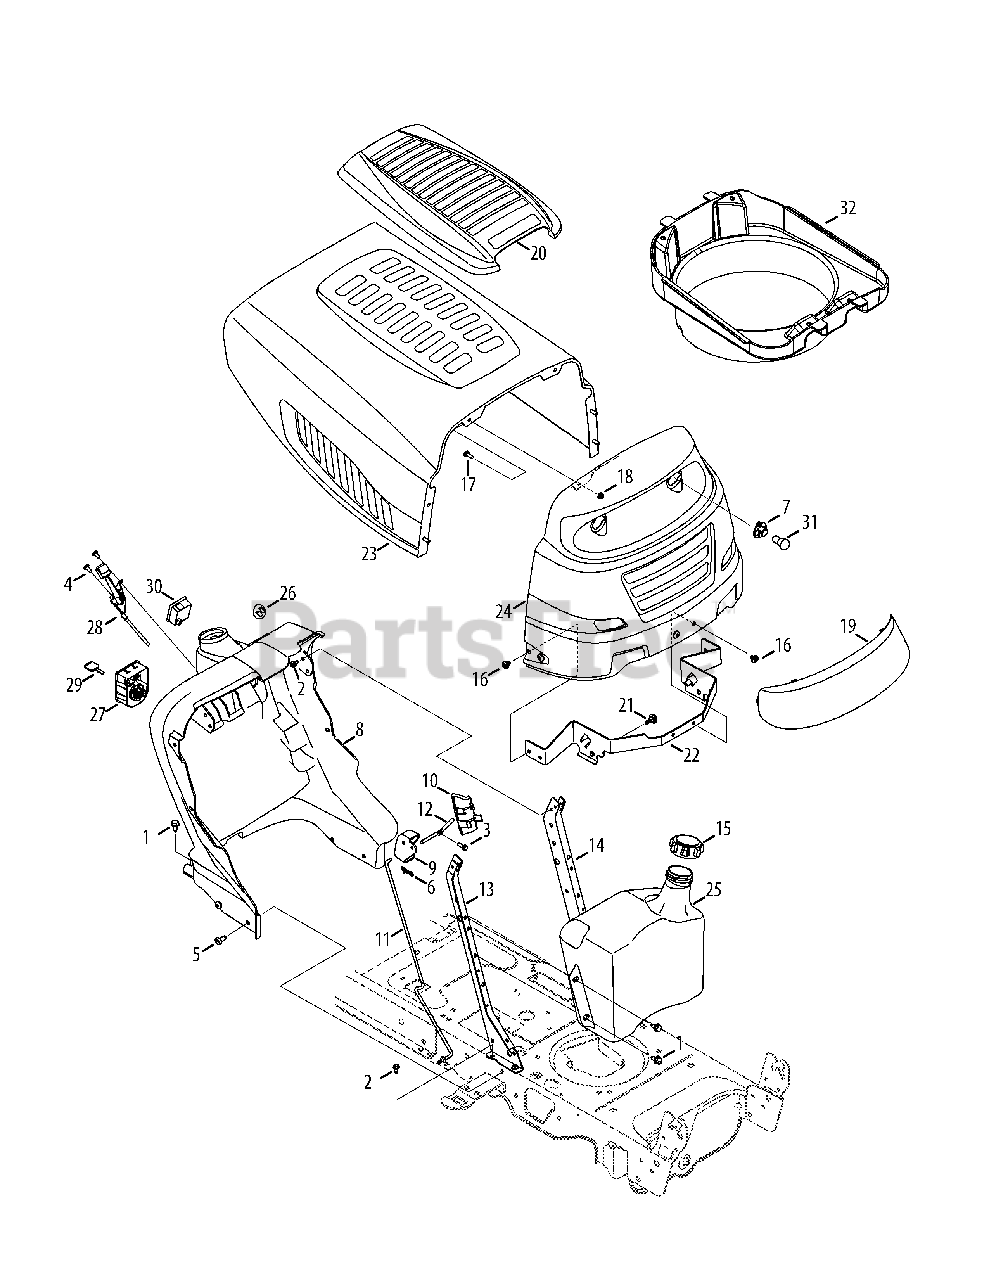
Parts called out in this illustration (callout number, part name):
1	Taptite Screw ,5/16-18x.750
2	Taptite Screw ,1/4-20x0.500
3	Hi-Lo Screw, 1/4-15x0.750
4	Screw, 1/4-14x0.625
5	Taptite Screw ,5/16-18x0.750
6	Bow Tie Cotter Pin
7	Lamp Socket
8	Dash Panel, No Sight Window
9	Dash Lever
10	Cruise Cover
11	Control Rod
12	Lever
13	RH Support Plate
14	LH Support Plate
15	Fuel Cap
15	Fuel Cap, EPA
16	Taptite Screw ,5/16-18x0.375
17	Hex Screw, 1/4-20x.620
18	Flangelock Nut, 1/4-20
19	Grill Lens
20	Hood Scoop
21	Shoulder Screw, .43X.29x5/16-18
22	Hood Pivot Bracket
24	Grill
25	Fuel Tank
25	Fuel Tank, EPA
26	Choke Plug
26	Choke Cable
27	Key Switch Module
28	Throttle/Choke Control
28	Throttle Cable
30	Hour Meter
32	Plenum
